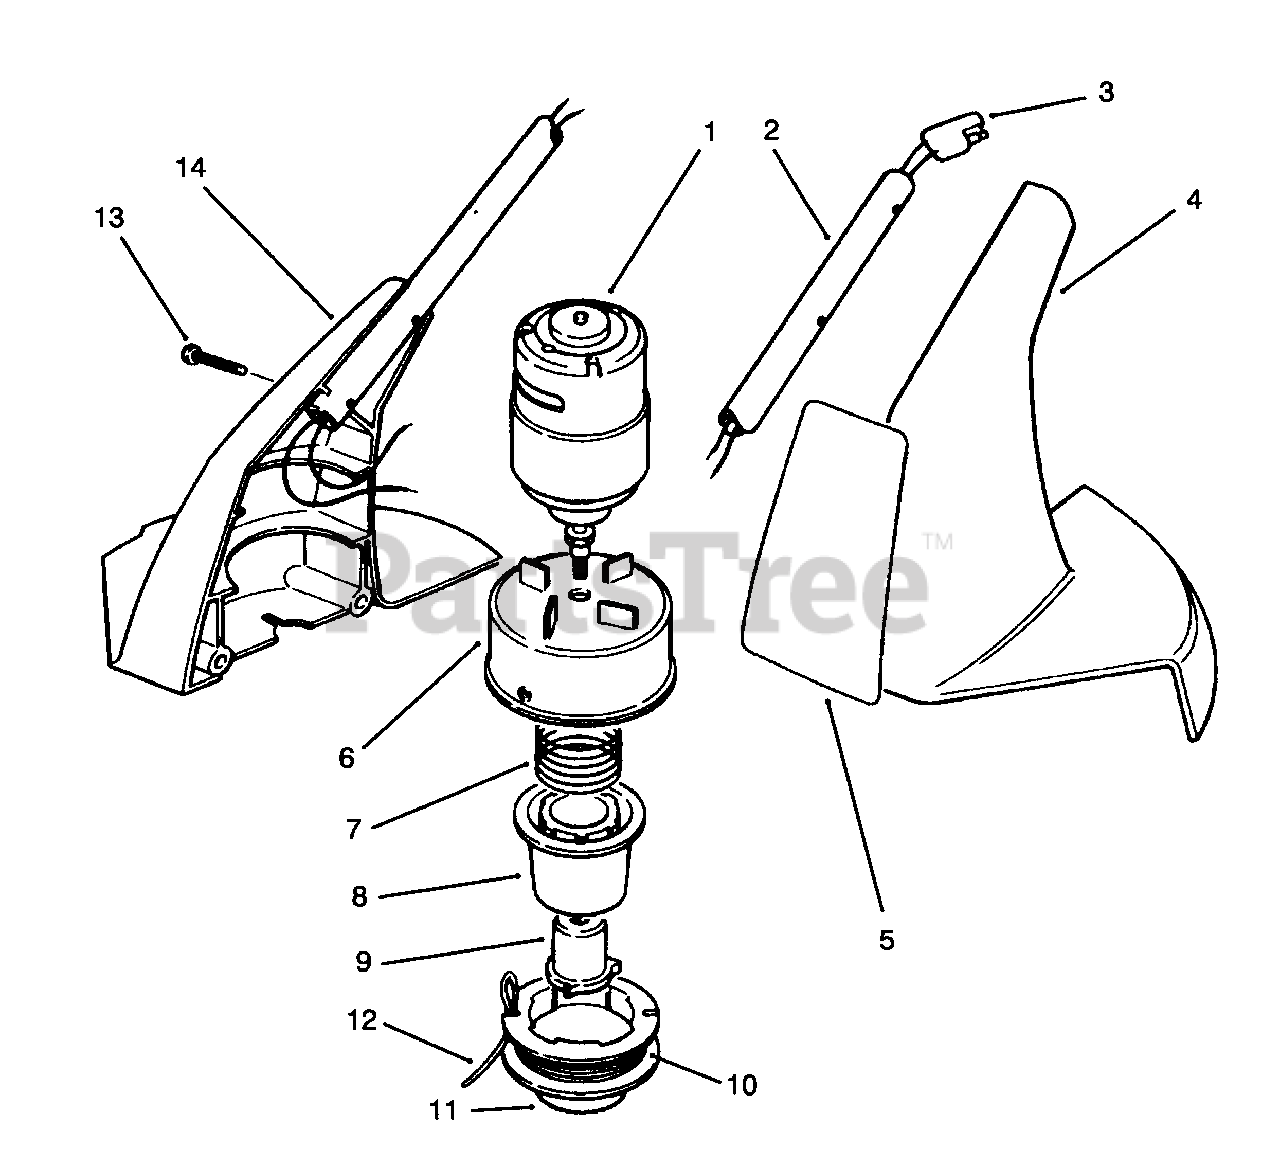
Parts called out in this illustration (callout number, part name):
1	Motor
2	Extension-Handle
3	Wiring Harness-Lower
4	Housing-Motor L.H.
5	Decal-7"
6	Drum w/Eyelet
10	Line-Cutting 12'.050 Dia. Prewound Spool(Incl. Ref. #11)
11	Spool-Empty
12	Line-Cutting 30'.050 Dia. in Coil
14	Housing-Motor R.H.
